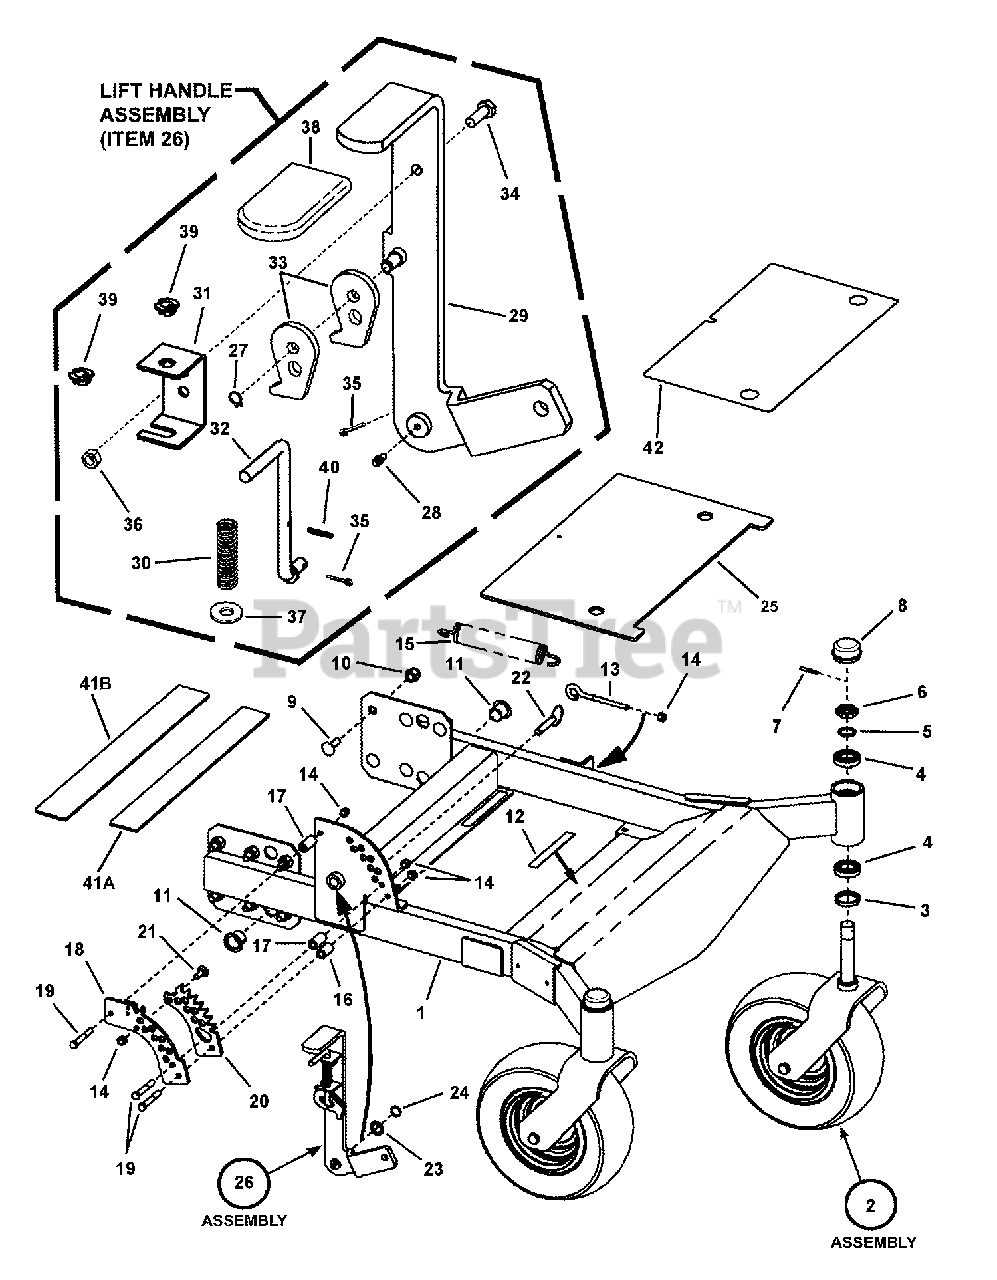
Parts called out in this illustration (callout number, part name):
1	WELDMENT, Front Frame
2	GROUP, Front Wheel (see Caster Wheel Assembly Page)
3	GREASE SEAL
4	BEARING, Tapered Roller
5	SPACER, Jackstaff
6	CASTLE NUT, 1-1/ UNF, GR B
7	ROLL PIN, 3/16 x 1-1/2"
8	CAP, Dust
9	BOLT, 1/2-13 x 1-1/2" Square Neck Carriage, GR 5
10	NUT, 1/2-13 Hex Nyloc
11	BUSHING, Teflon
12	PAD, Floor Pan
13	EYEBOLT, 3/8-16 x 3"
14	NUT, 3/8-16 HEX NYLON LOCK
15	SPRING, Extension, Lift Assist
16	SPACER, Lift Adjust (1.08" Long)
17	SPACER, Lift Adjust (1.43" Long)
18	WELDMENT, Height Adjust
19	BOLT, 3/8-16 X 2-1/2" GD5 CZ
20	BRACKET, Deck Lift Detent
21	BOLT, 3/8-16 x 1" Square Neck Carriage, GR 5
22	CLIP, Roll Pin, 1/2"
23	WASHER, .77 I.D. Flat
24	RING, 3/4" External Retaining
25	FLOORPAN
26	ASSY, Deck Lift Handle (Incl. items 27 thru 40)
27	RING, .375" Diameter External Retaining
28	LUBE FITTING, 3/16"
29	WELDMENT, Deck Lift Handle
30	SPRING, Neutral Return
31	BRACKET, Handle Support
32	ROD, Latch
33	STOP, Latch
34	SCREW, 5/16-18 x 1" Hex Head Cap, GR 2
35	PIN, 3/32 x 1/2" Cotter
36	NUT, 5/16-18 Hex Center Lock
37	WASHER, 3/8" Flat SAE
38	COVER, Plastic
39	BUSHING, 3/8" Plastic
40	ROLLPIN,1/8 x 7/8"
41A	MAT, Footpan (22-11/16" long)
41B	MAT, Foot Pan (24-9/16" long)
42	MAT, Foot Pan
